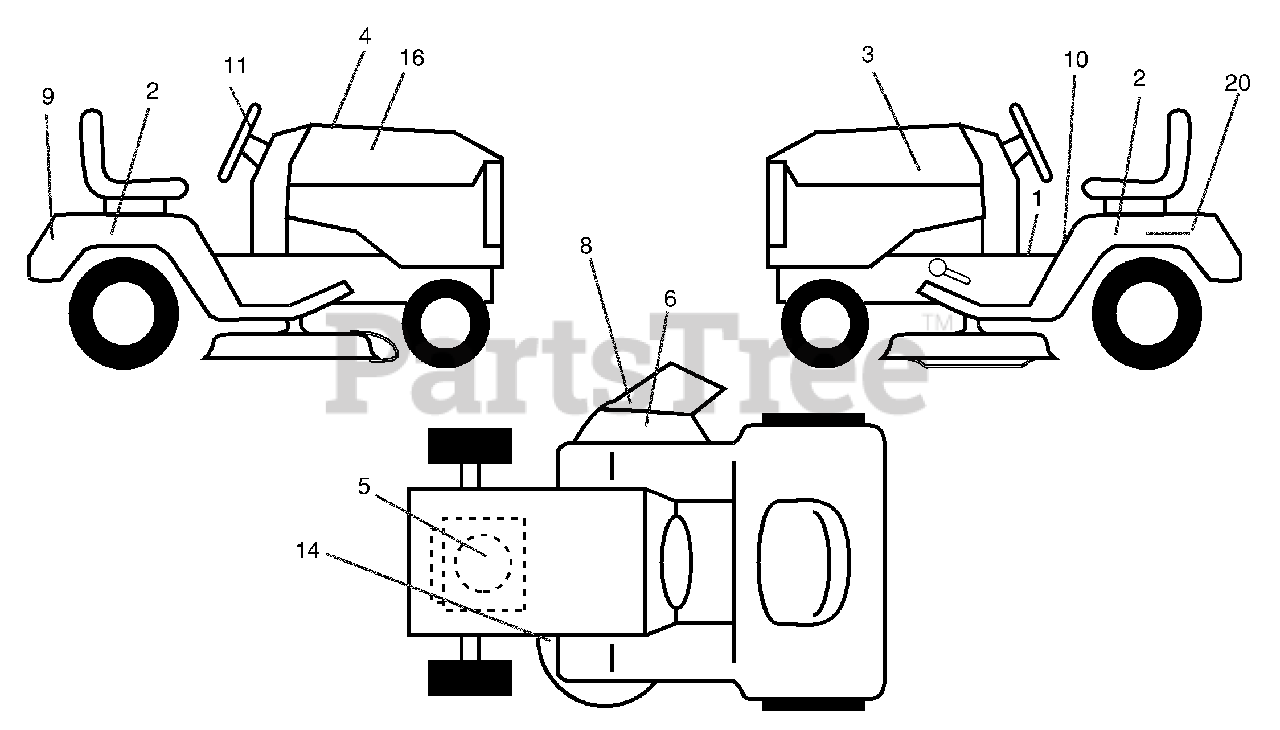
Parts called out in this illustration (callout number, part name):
2	Decal Fender Side
3	Decal Hood LH
4	Decal Hood RH
5	Decal HP Engine
6	Decal Deck "B" 42"
8	Decal Warning Mult-Language
9	Decal Fender Logo
10	Decal Fender Danger E/F
11	Decal Ins Strg Whl
14	Decal V-Belt Schematic
16	Decal Replace
20	Decal Bat Dan/Psn
